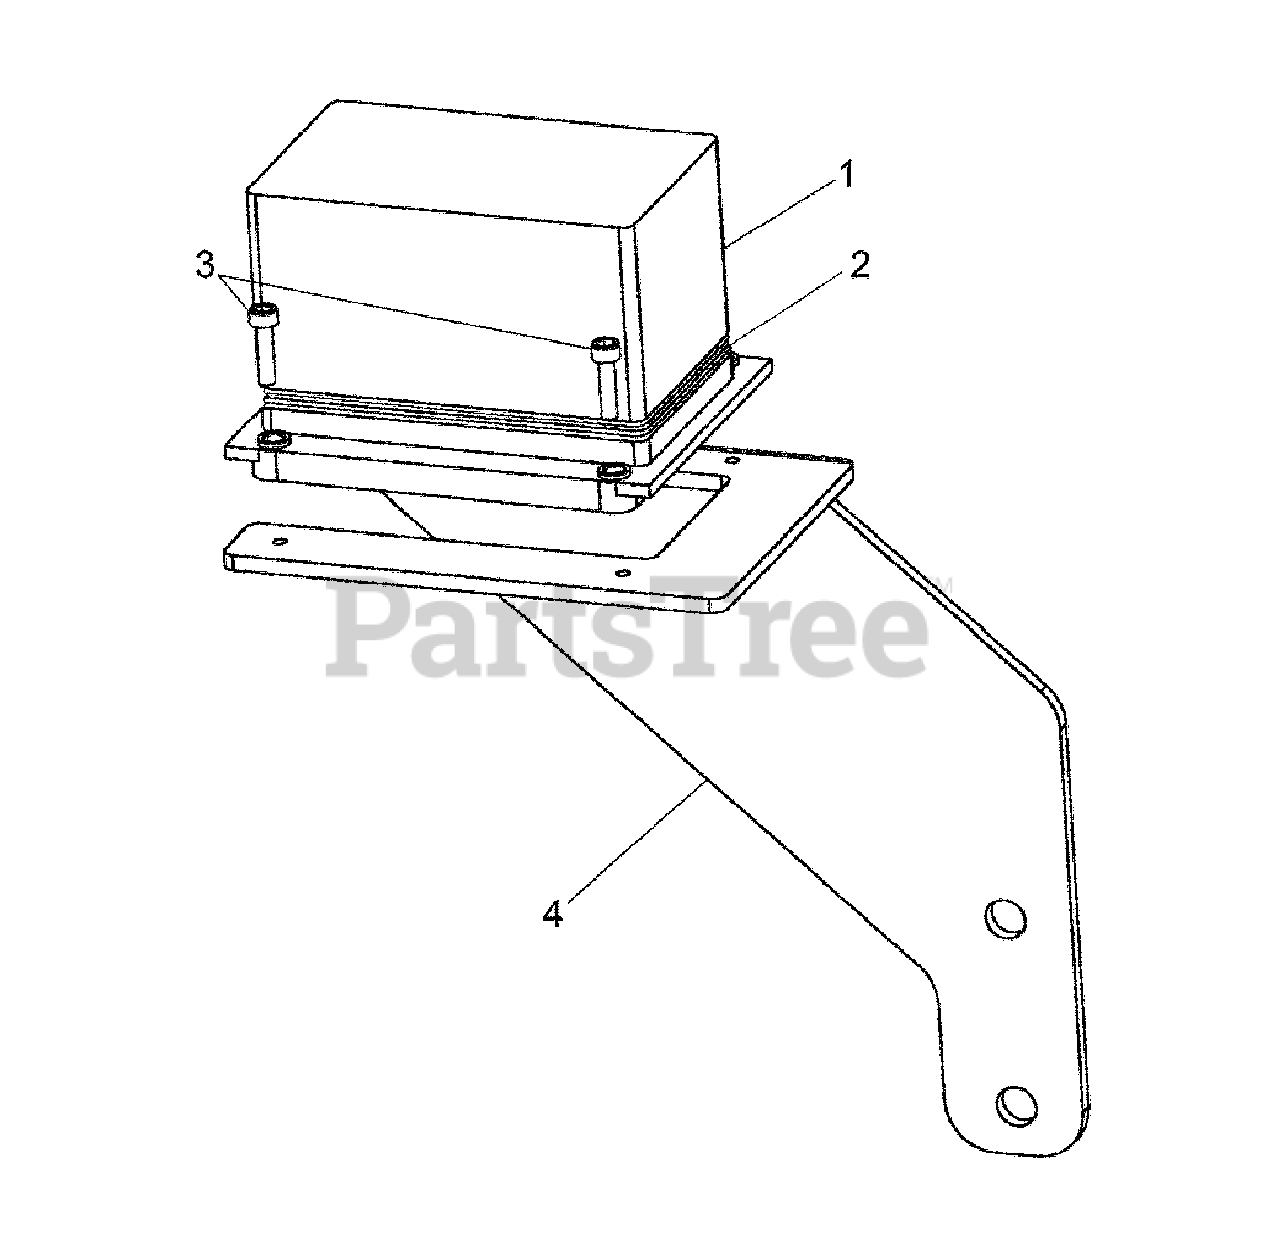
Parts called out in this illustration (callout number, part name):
1	COVER
2	SEAL
3	SCREW
4	BRACKET
